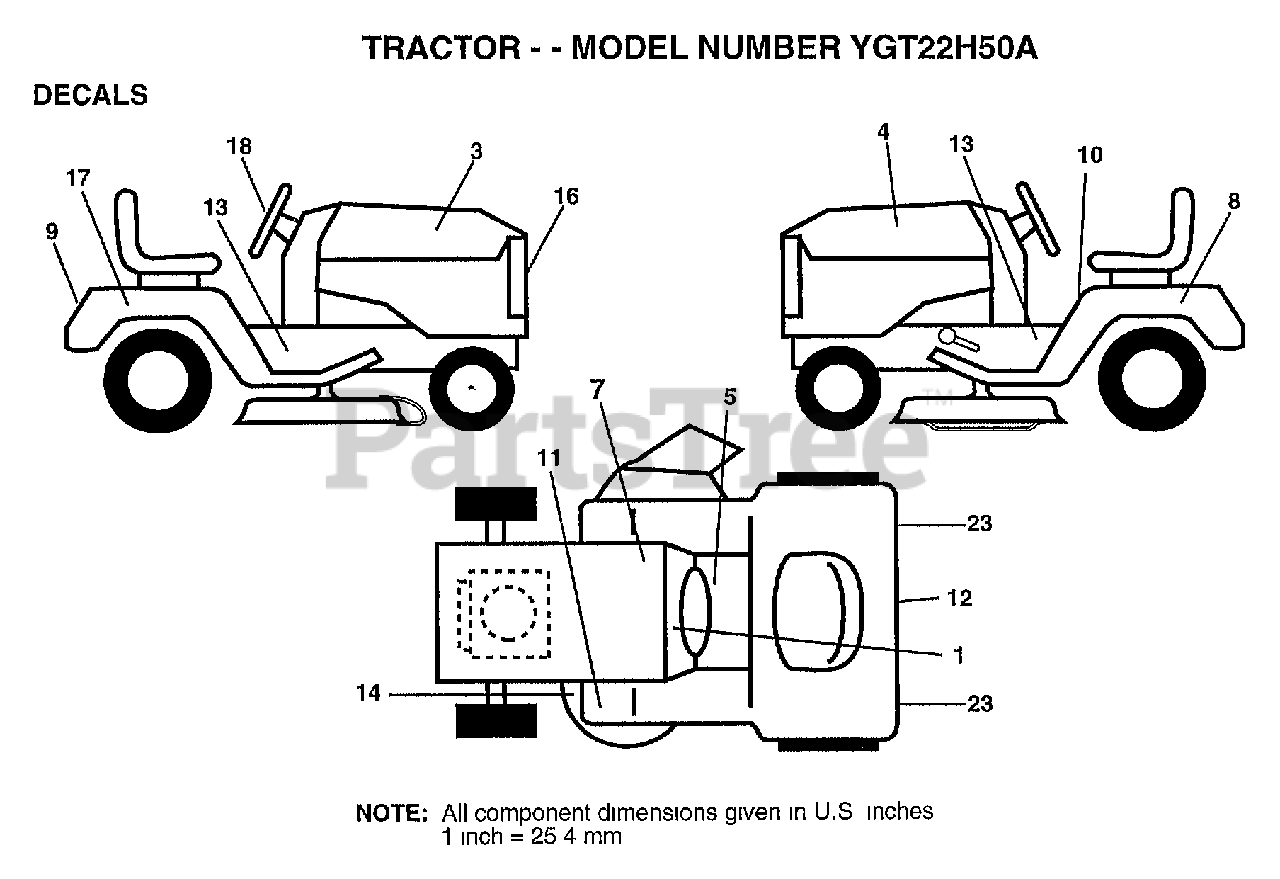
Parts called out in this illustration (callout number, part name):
1	"DECAL-INST,OPER"
3	"DECAL HOOD,RH"
4	DECAL HOOD LH
5	DECAL BRAK PARK
7	DECAL.BATRY.3-3908
8	DECAL FENDER LH
9	DECAL FENDER
10	"DECAL DANGER,FEND"
12	DECAL D-BAR CNTRL
13	DECAL CHASSIS 50
14	"DECAL.V.BELT.44"""
16	DECAL GRILLE
17	DECAL FENDER RH
18	DECAL INS STRG WH
23	REFLECTOR-TAIL YT
